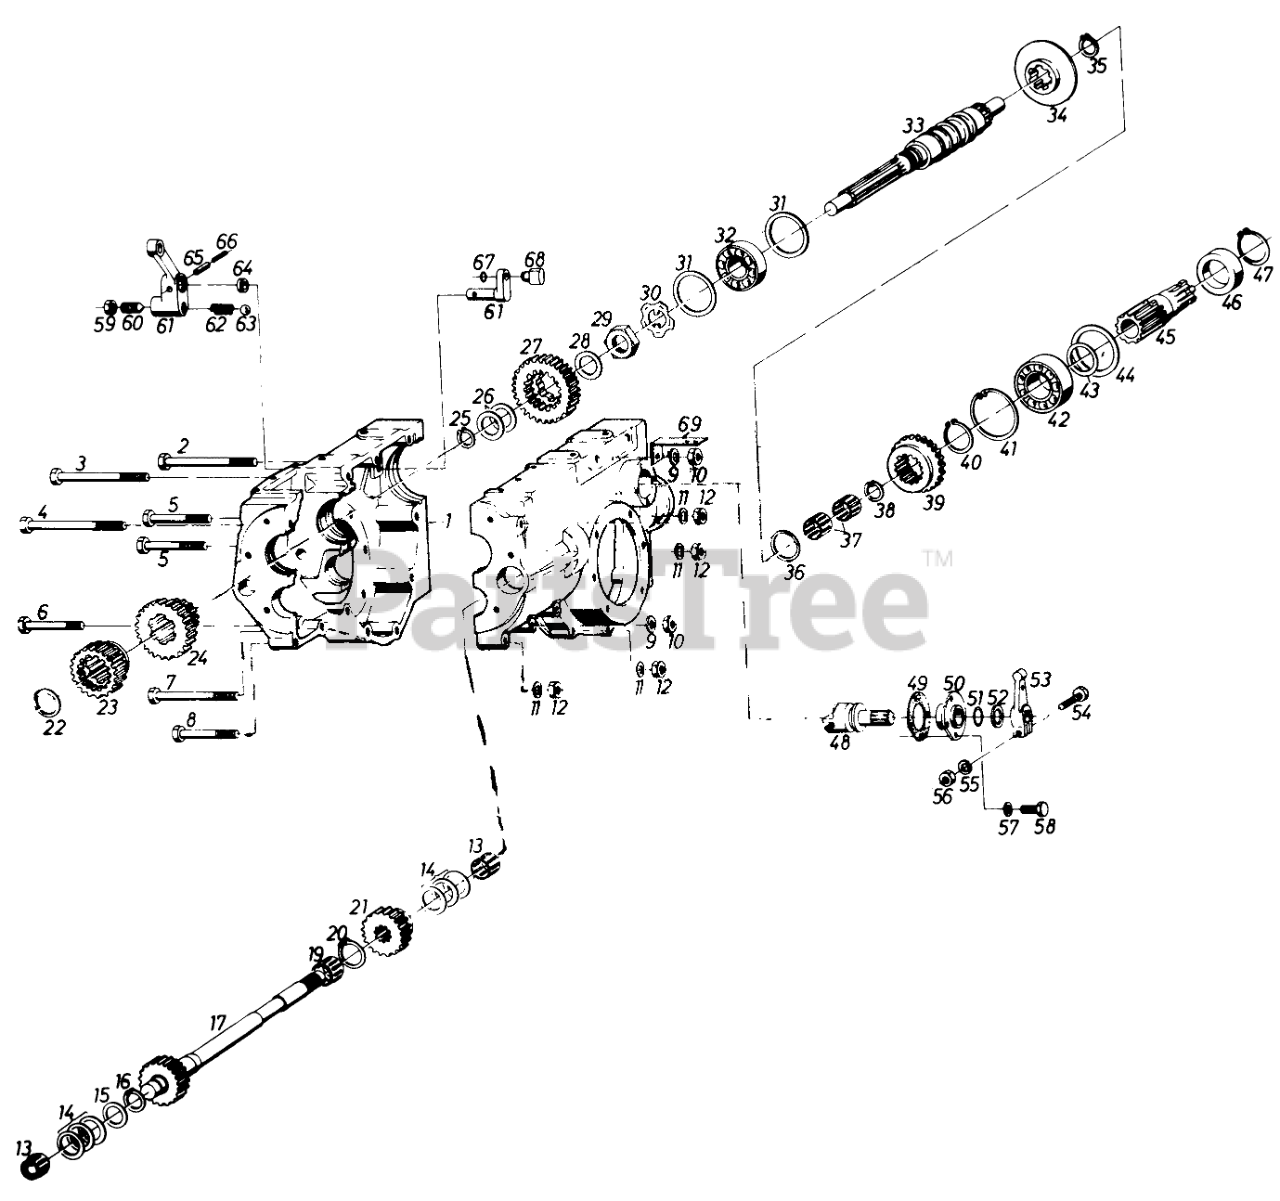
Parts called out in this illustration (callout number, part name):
1	Washer
2	Screw
3	Bolt
4	Bolt
5	Screw
6	Screw
7	Screw
8	Screw
9	Washer
10	Nut
11	Lockwasher
12	Nut
13	Needle Bushing
14	Shim (18 X 25 X 1 DIN 988)
14	Shim (18 X 25 X 0.5)
14	Shim
15	Shim
16	Retaining Ring
17	Counter Shaft
19	Needle Bearing
20	Retaining Ring
21	Counter Pinion
22	Shim (15 X 21 X 0.5 DIN 988)
22	Shim (15 X 21 X 0.2 DIN 988)
23	Pinion 3. and 4. Speed
24	Pinion 1. and 2. Speed
25	CIRCLIP
26	SHIM
27	Pinion
28	Shim
29	Nut
30	Lock Plate
31	Retaining Ring
32	Ball Bearing
33	Worm Shaft Counter Clockwise
34	Brake Washer
35	Retaining Ring
36	Washer
37	NEEDLE CAGE
38	SEEGER V-RING
39	Pinion
40	Retaining Ring
41	Retaining Ring
42	Ball Bearing
43	O-Ring
44	Shim (63 X 80 X 0.2 DIN 988)
44	Shim (63 X 80 X 0.5 DIN 988)
45	P.T.O. Shaft
46	Bushing
47	Retaining Ring
48	Brake Peg
49	Gasket
50	Cover
51	O-Ring
52	Spacer
53	Brake Lever
54	Screw
55	Lock Washer
57	Lock Washer
61	Lever Assy
62	Spring
64	V-Ring
65	Spring Pin
66	Spring Pin
67	Retaining Ring
